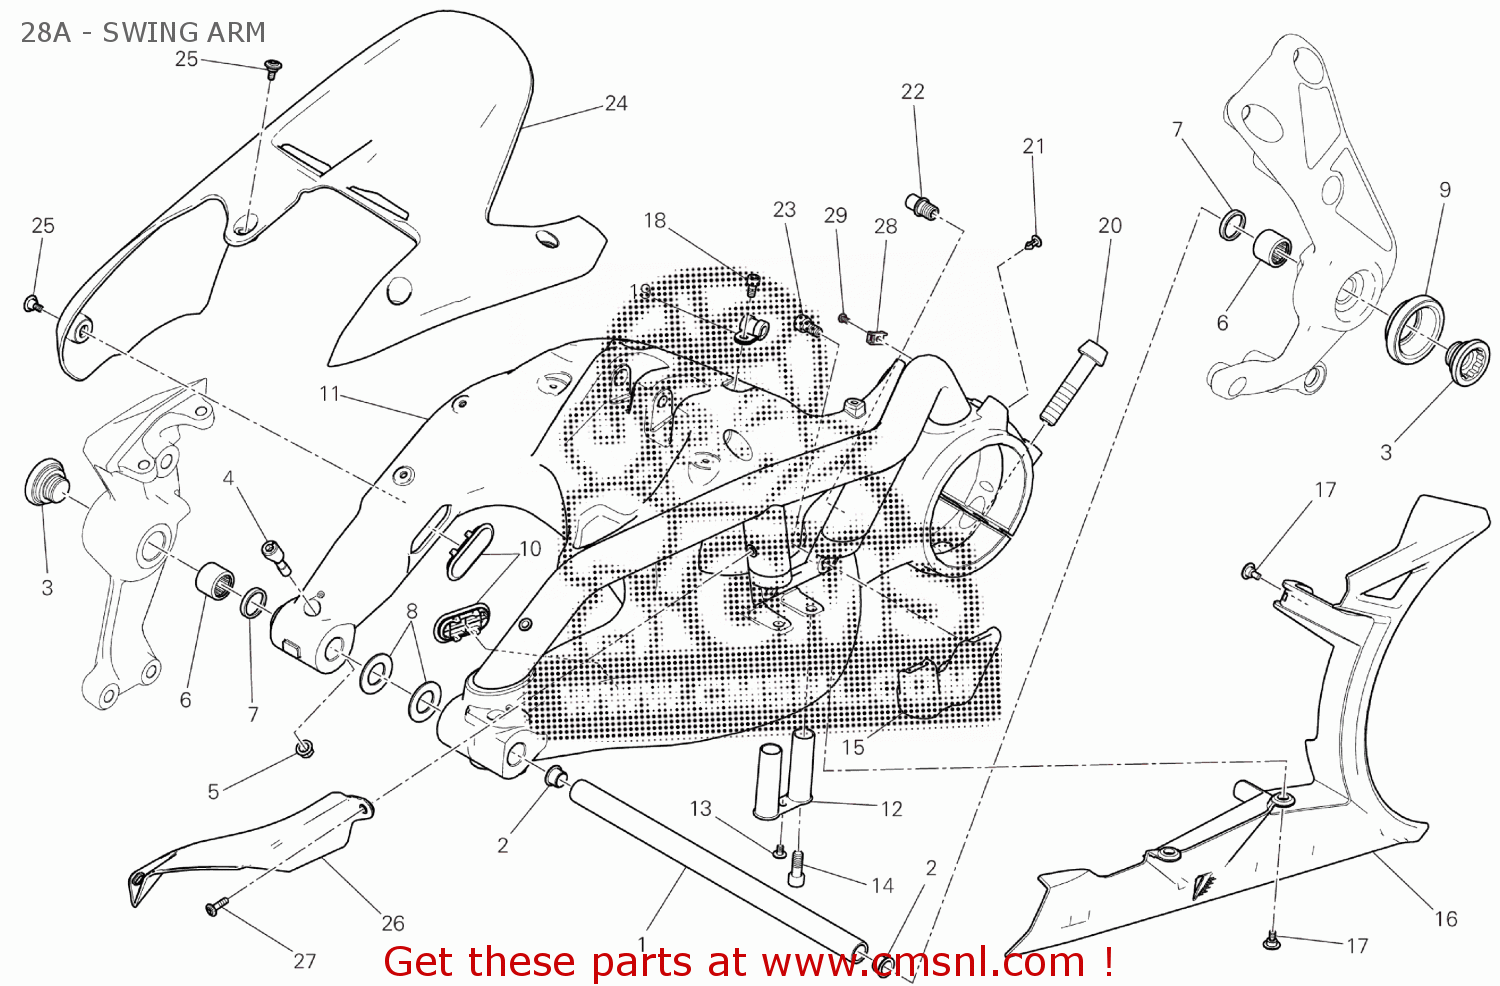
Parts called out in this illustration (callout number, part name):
1	AXLE, REAR SWING ARM
2	BUSH WITH COLLAR
3	PLUG
4	CLAMP
5	NUT M8
6	BEARING, NEEDLE
7	SEAL RING 20X26X4
8	THRUST WASHER 20.5X36X1.8 MM
9	PLUG
10	CAP, SWINGARM COVER
11	REAR SWINGING ARM
12	PLUG
13	SCREW
14	SCREW
15	FORK
16	GUARD
17	SCREW
18	SCREW TCEI M6X12
19	HOSE CLAMP 8 MM
20	SCREW, SPECIAL
21	PLUG
22	PIN
23	SCREW M8X16
24	REAR MUDGUARD
25	SCREW
26	VERTICAL TIMING BELT COVER
27	SCREW TBEI M5X18
28	HOSE GUIDE
29	SCREW TBEI M4X10
